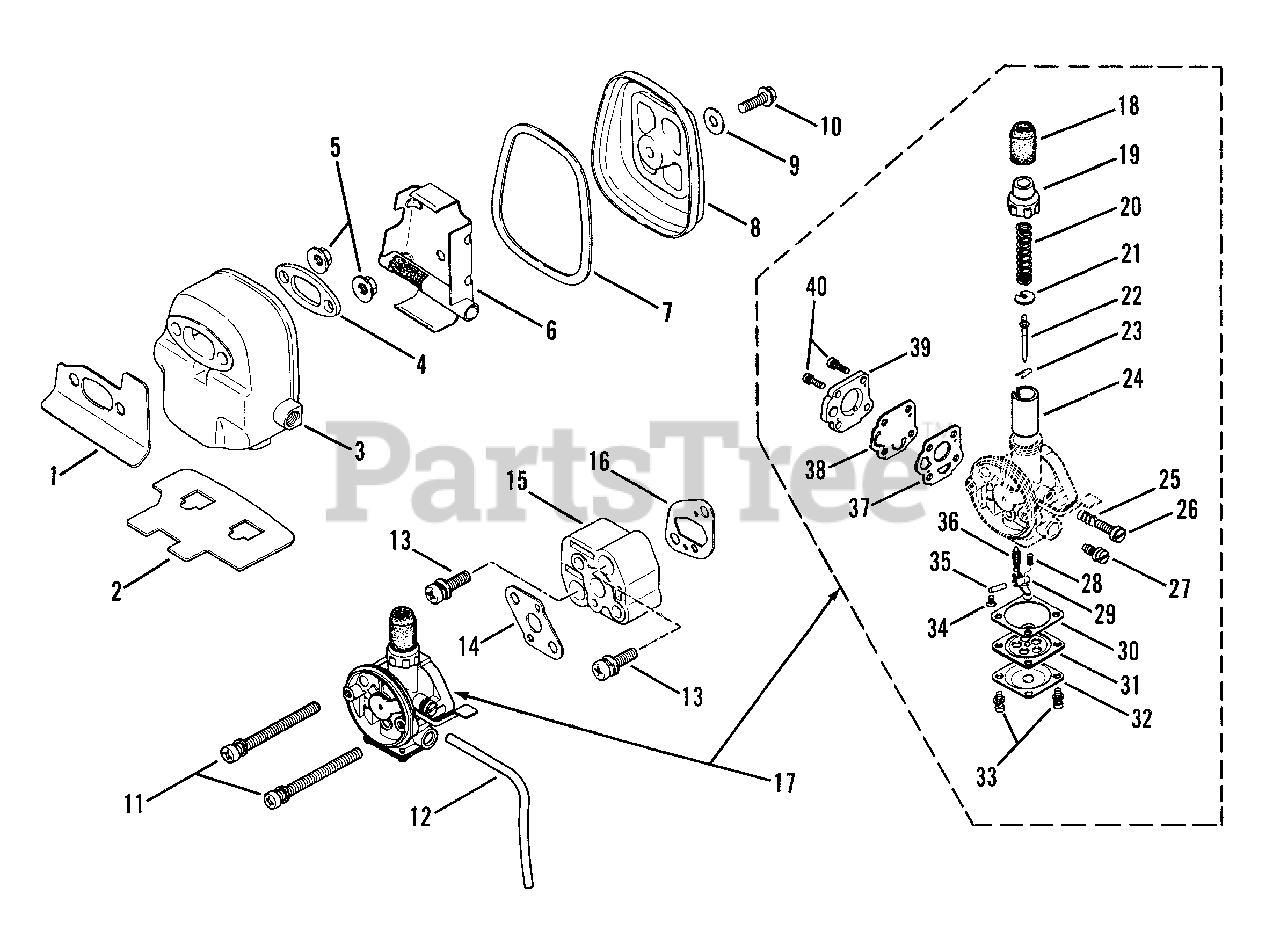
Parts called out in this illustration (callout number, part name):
1	GASKET, Muffler
2	GASKET
3	BODY, Muffler
4	PLATE, Muffler
5	LOCKNUT, Sems
6	SPARK ARRESTOR ASSM'Y
8	COVER, Muffler
10	BOLT, Flange
11	SCREW/WASHER, Carb.
12	TUBE, Overflow
13	SCREW/WASHER
14	GASKET, Carburetor
15	INSULATOR, Carburetor
16	GASKET, Insulator
17	CARBURETOR ASSEMBLY
18	CAP, Rubber
19	CAP, Mixing Chamber
20	SPRING, Throttle
21	RETAINER, Spring
22	NEEDLE, Jet Assembly
23	CLIP, Needle
24	VALVE, Throttle
25	SPRING, Throttle Adj. Screw
26	SCREW, Throttle Adj.
27	NEEDLE, Main Jet Assm'y.
28	SPRING, Inlet Valve
29	ARM, Float
30	GASKET, Main Diaphragm
31	DIAPHRAGM, Main Assm'y.
32	COVER, Main Diaphragm
34	SCREW, Float Pin Set
35	PIN, Float
36	VALVE, Float
37	GASKET, Pump Cover
38	DIAPHRAGM, Pump
39	COVER, Pump
